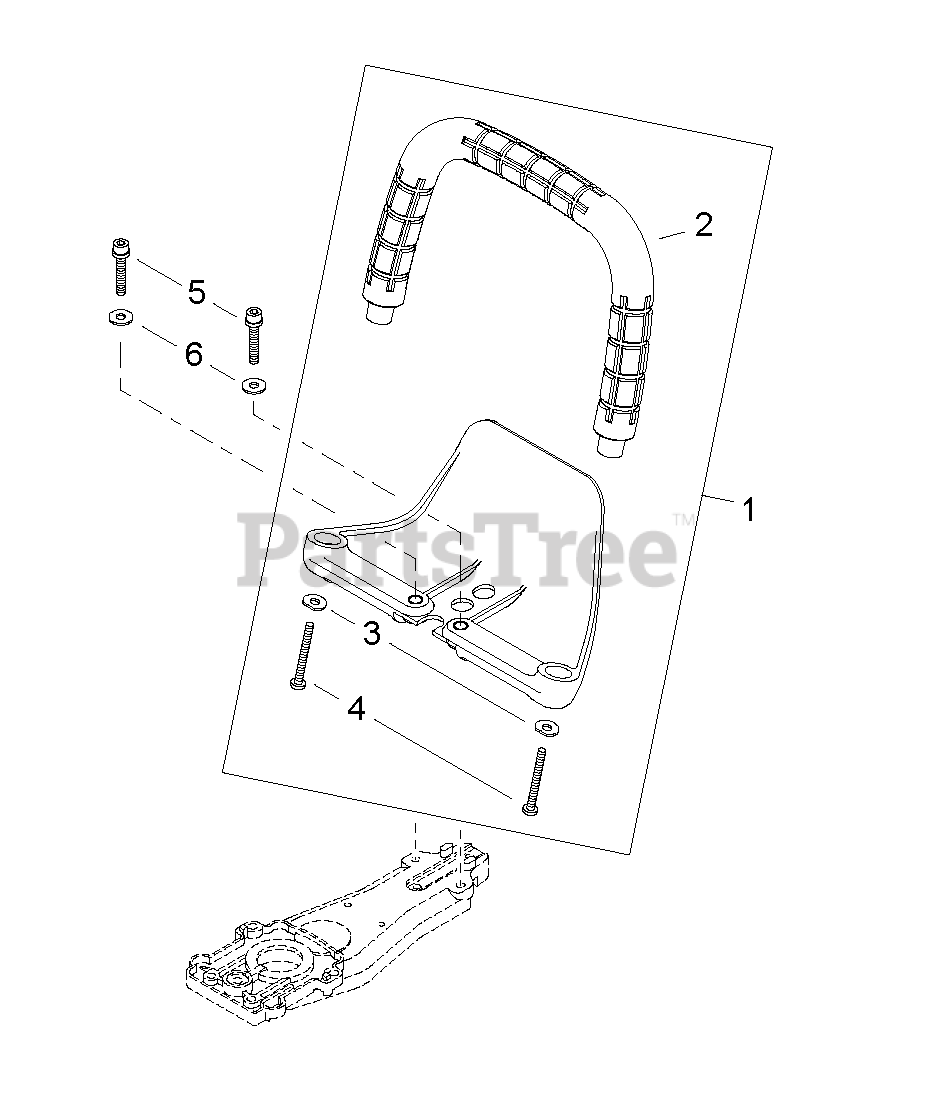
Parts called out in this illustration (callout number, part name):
1	HANDLE ASSY, FRONT
2	HANDLE, FRONT
3	WASHER
4	BOLT, TAPPING 5
5	BOLT M6×30
6	WASHER Ø16ר6.5×1.6 MM
